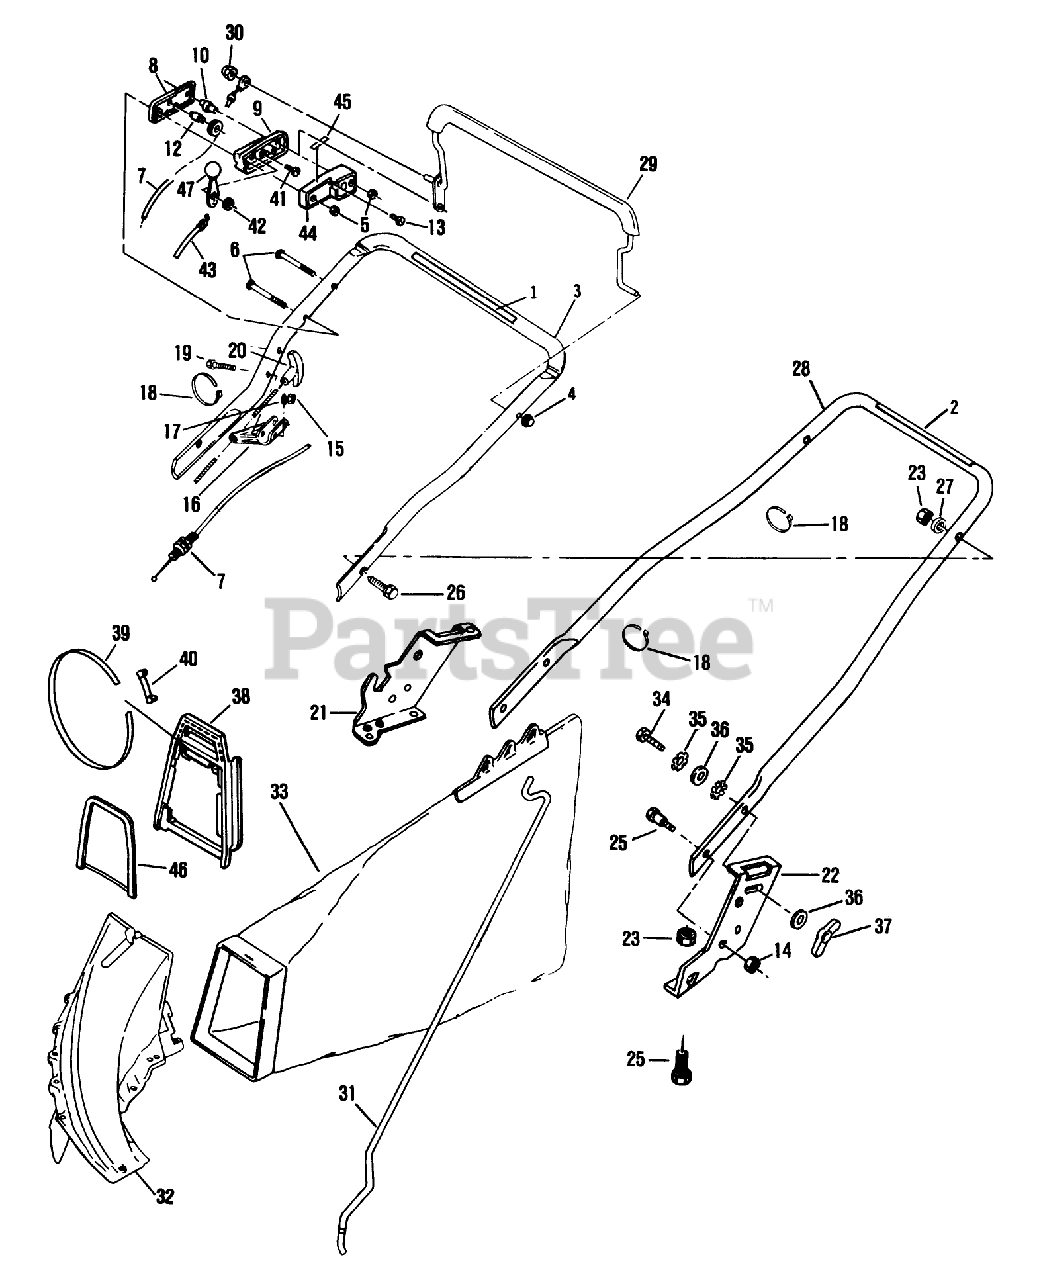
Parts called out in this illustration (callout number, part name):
3	HANDLE SECTION
5	NUT C/LOCK E
7	CONTROL CABLE WES
8	OUTER CONTROL CASE
10	COLUMN
11	PULLEY PL
12	PIN SKF
13	SCREW
14	NUT-JAM, LOCKING
15	LOCKNUT E
17	WASHER
20	HANDLE START UM&D
23	NUT-LOCK F
25	BOLT
27	WASHER-CURVED
29	CONTROL LEVER ARG
30	NUT ACORN
31	ROD GRASSBAG
32	CHUTE ASSY
33	Grass Bag
35	LOCK WASHER LARSON
36	WASHER
37	NUT-WING
38	CHUTE - ADAPTER
41	SCREW
42	WASHER-SPRING
43	CABLE THROT WES
46	CHUTE BRACE
47	LEVER&KNOB AY WES
